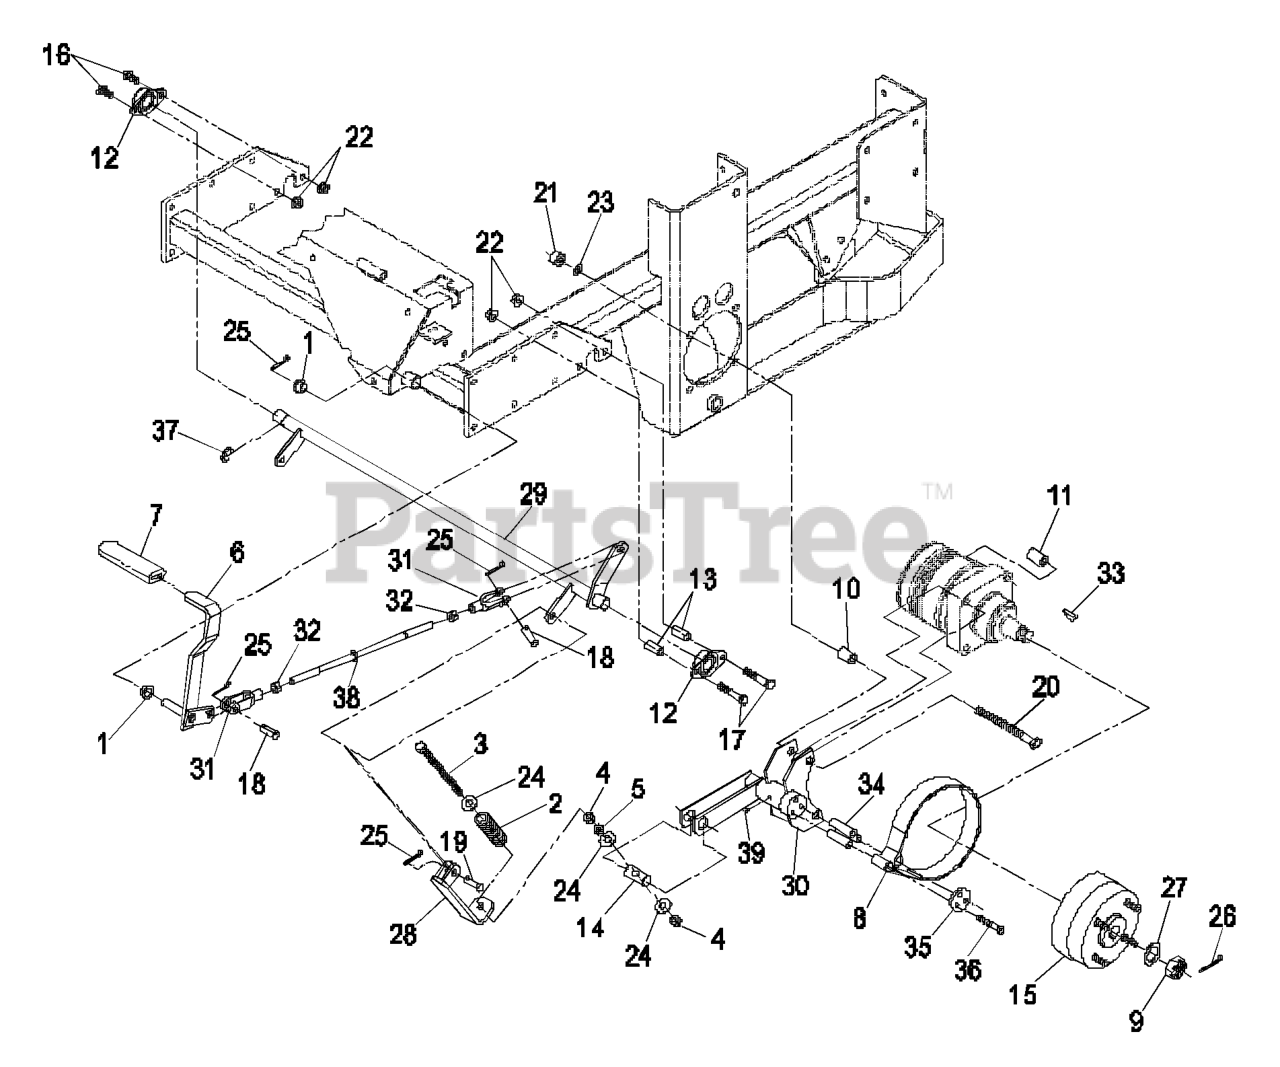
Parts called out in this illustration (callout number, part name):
1	BEARING-CONTROL
2	SPRING-BRAKE
3	BOLT-TAP, HH
4	NUT-LOCK, NI
5	NUT-JAM
6	BRAKE LEVER AND GRIP ASM
7	GRIP-LEVER
10	SPACER-WHEEL, SHORT
11	SPACER-WHEEL, LONG
12	BEARING-FLANGE, SIDE
13	SPACER-RETAINER, BRAKE
14	PIN-TRUNION
15	WHEEL HUB ASM
16	SCREW-HH
17	SCREW-HH
18	PIN-CLEVIS
19	PIN-CLEVIS
20	SCREW-HH
22	NUT-HHF, WHIZ
23	WASHER-LOCK
24	WASHER-FLAT
25	PIN-COTTER
26	PIN-COTTER
27	WASHER-SPACER
28	LINKAGE-BRAKE, LOWER
30	BRAKE-WIDE
31	YOKE-LINKAGE, BRAKE
32	NUT-HEX
33	KEY-WOODRUFF
35	RETAINER-BAND, BRAKE
36	SCREW-HH
38	ROD-BRAKE
39	FITTING-GREASE
